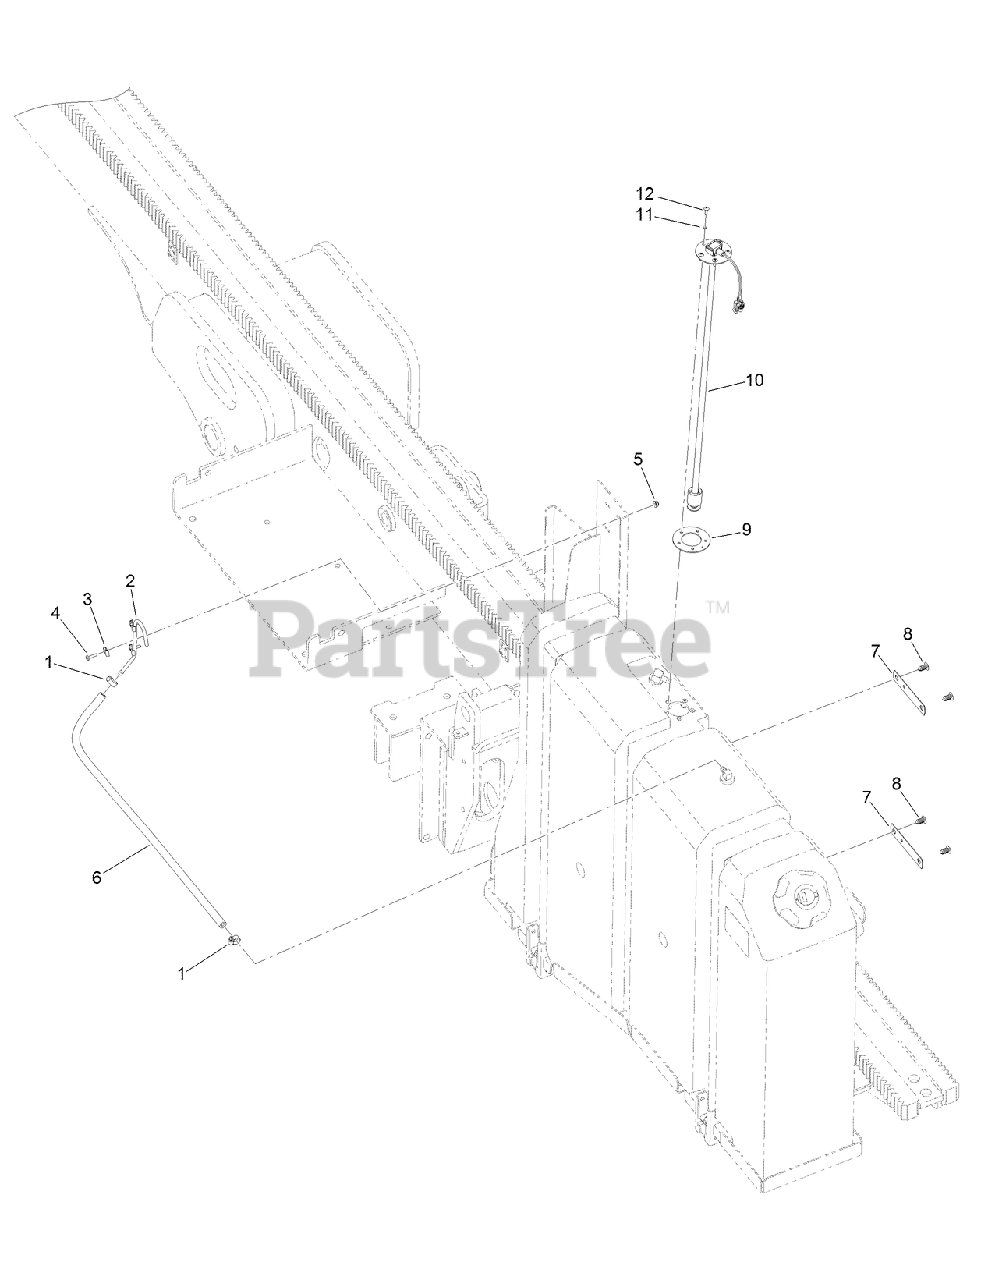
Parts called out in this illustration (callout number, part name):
1	CLAMP-WORM
2	TUBE-VENT
3	CLAMP-CONDUIT
4	SCREW-HWH
5	NUT-HF
6	HOSE-TANK, EXPANSION
7	PLATE-GUIDE, HOSE
8	RIVET-PUSH
9	GASKET-FUEL, VITON
10	GAUGE-FUEL, FLOAT
11	WASHER-LOCK
12	SCREW-PTH
